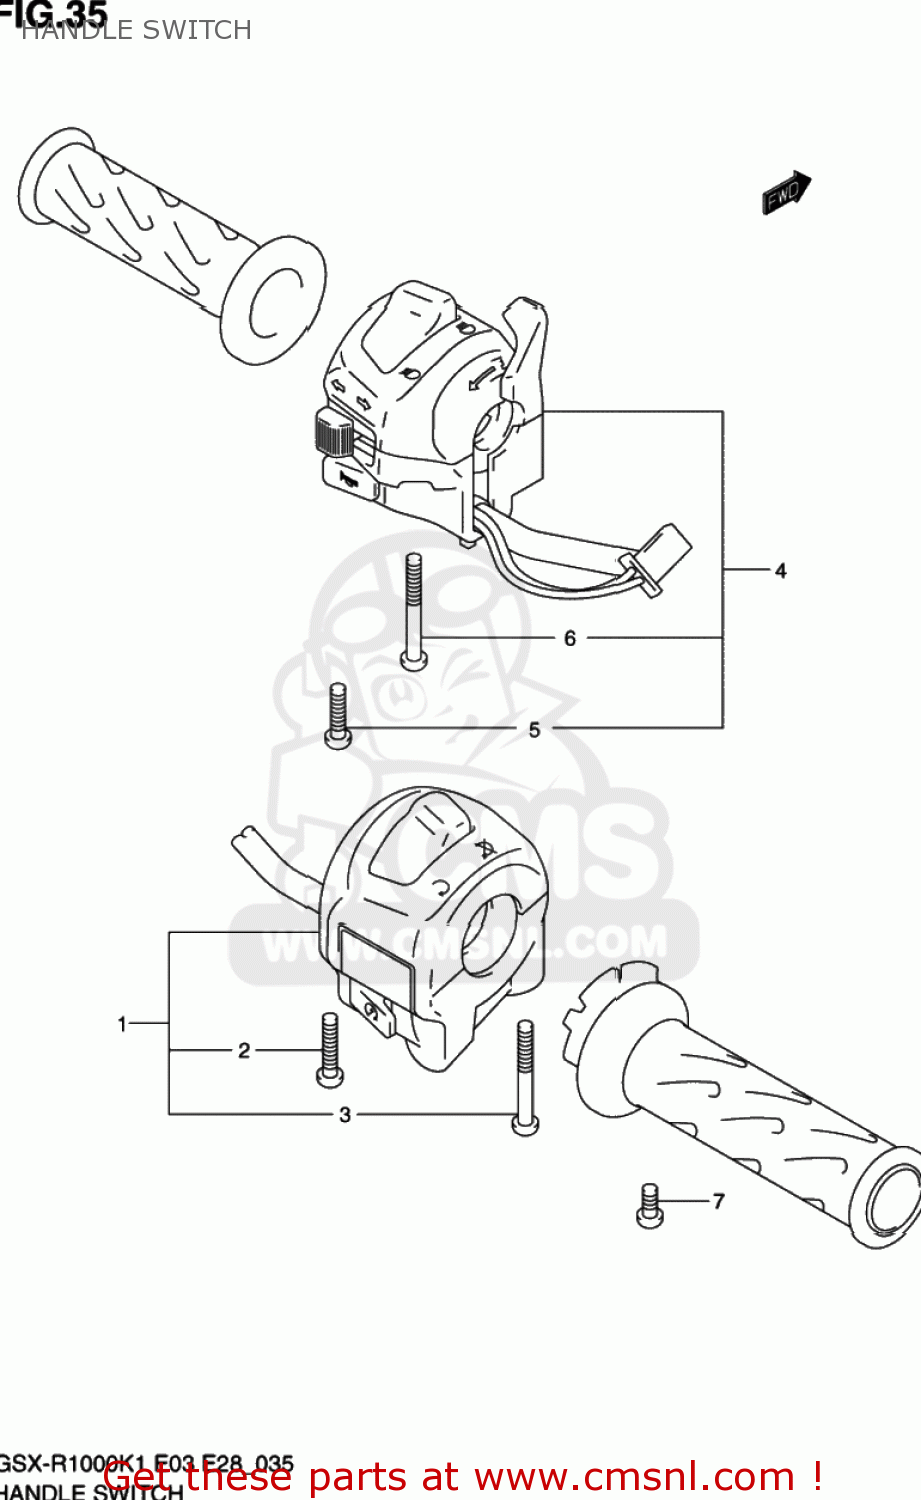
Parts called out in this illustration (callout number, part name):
1	SWITCH ASSY,HANDLE,R
2	SCREW
3	SCREW
4	SWITCH ASSY,HANDLE,L
5	SCREW
6	SCREW, 5X45
7	SCREW
